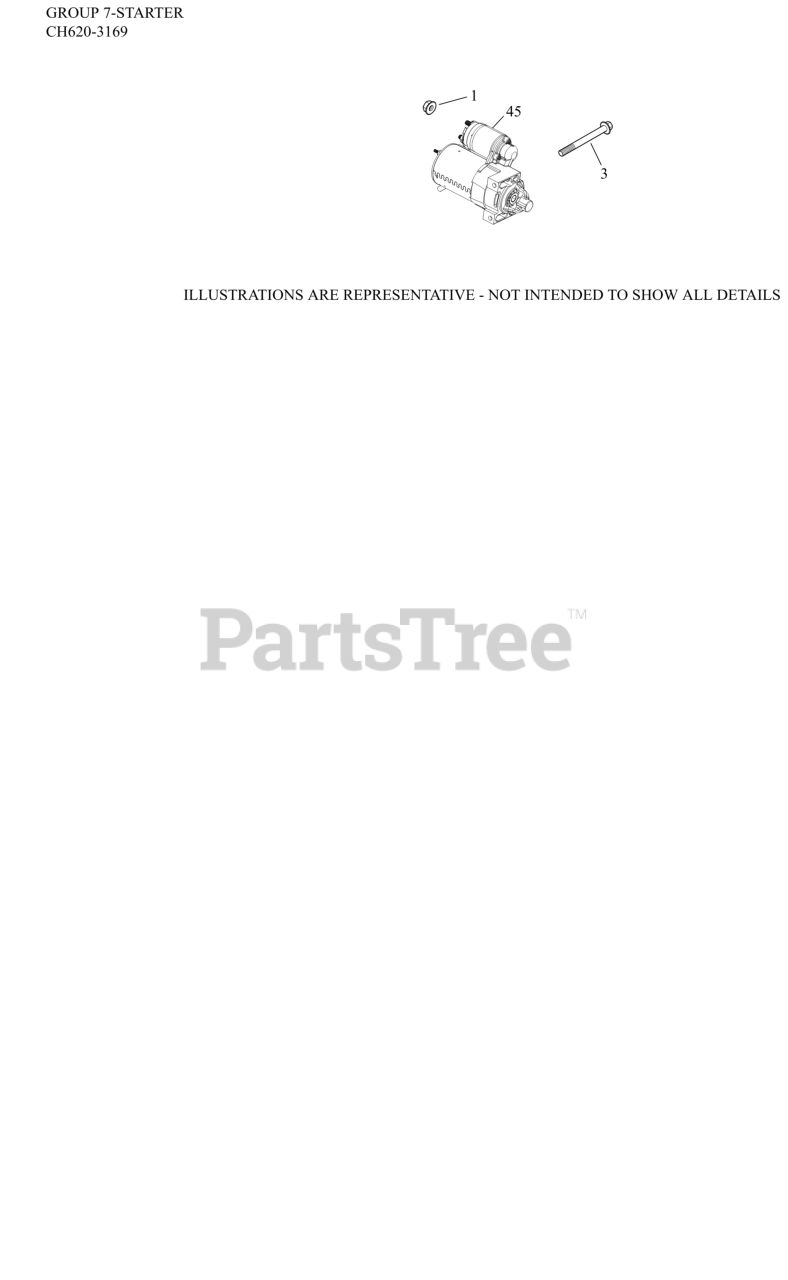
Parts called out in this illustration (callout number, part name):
1	NUT, FLG M8X1.25
3	SCREW, FLG M8X1.25X80
45	STARTER, SOLENOID SHIFT
